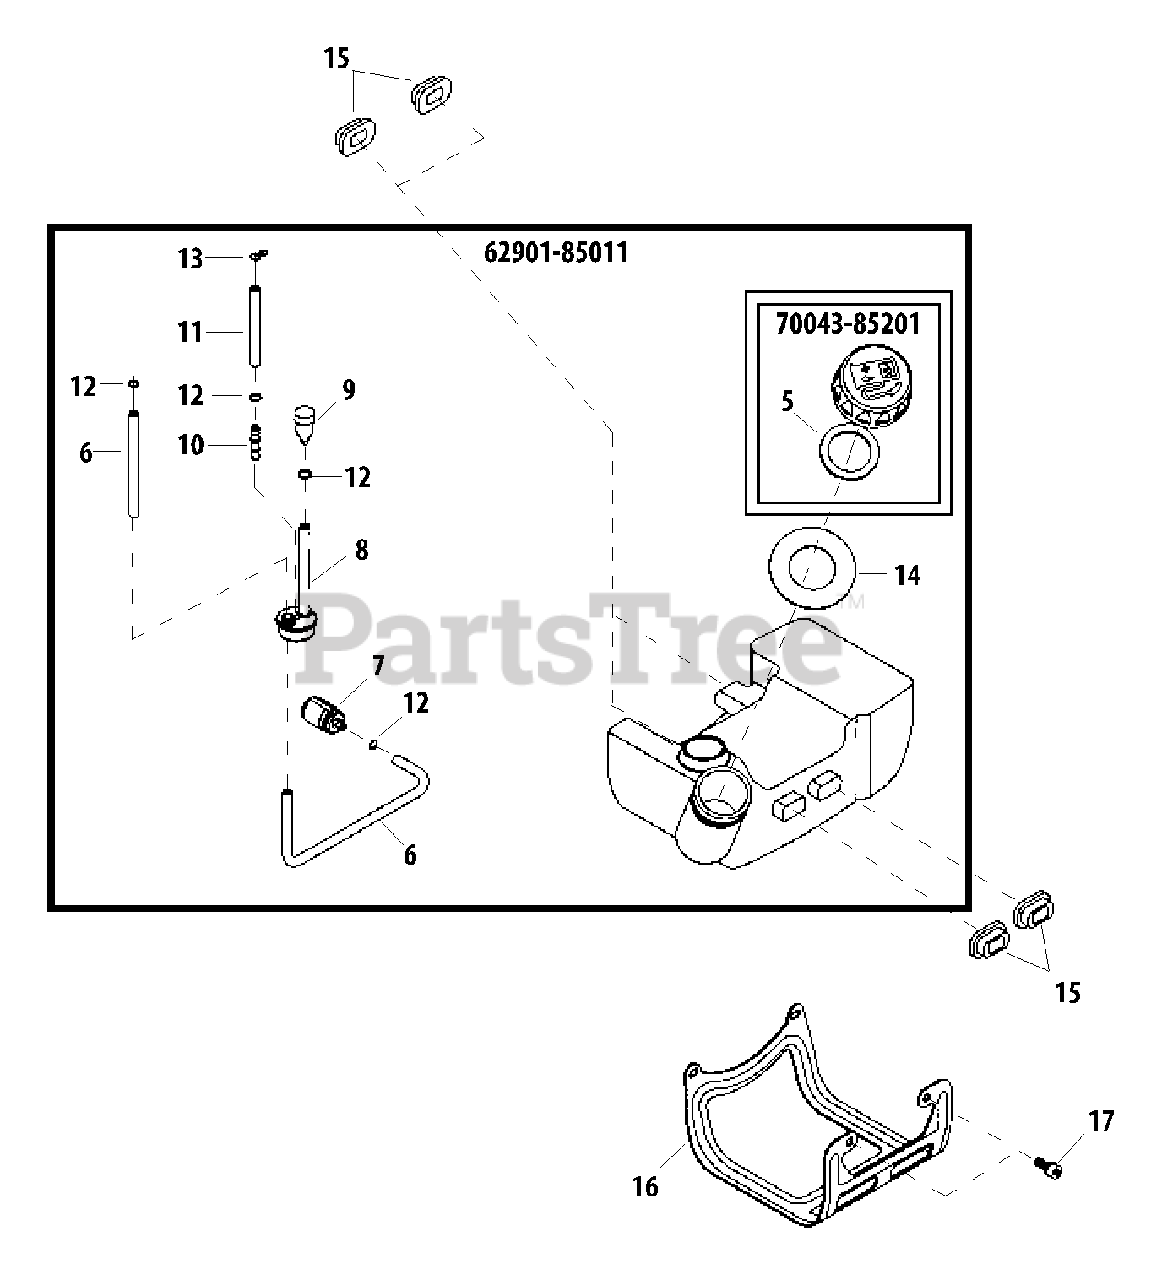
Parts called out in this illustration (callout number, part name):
5	GASKET, FUEL CAP
6	PIPE, FUEL 3.3×6×160
7	FILTER, FUEL 125-528
8	GROMMET
9	VENT ASSY
10	CONNECTOR, PIPE
11	PIPE, FUEL RETURN
12	CLIP Ø6
13	CLIP, SPRING Ø5.2
14	PLATE, CAUTION
15	CUSHION, FUEL TANK
16	GUARD, METAL FUEL TANK
17	BOLT 5×8
62901-85011	FUEL TANK ASSY
70043-85201	CAP ASSY, FUEL
